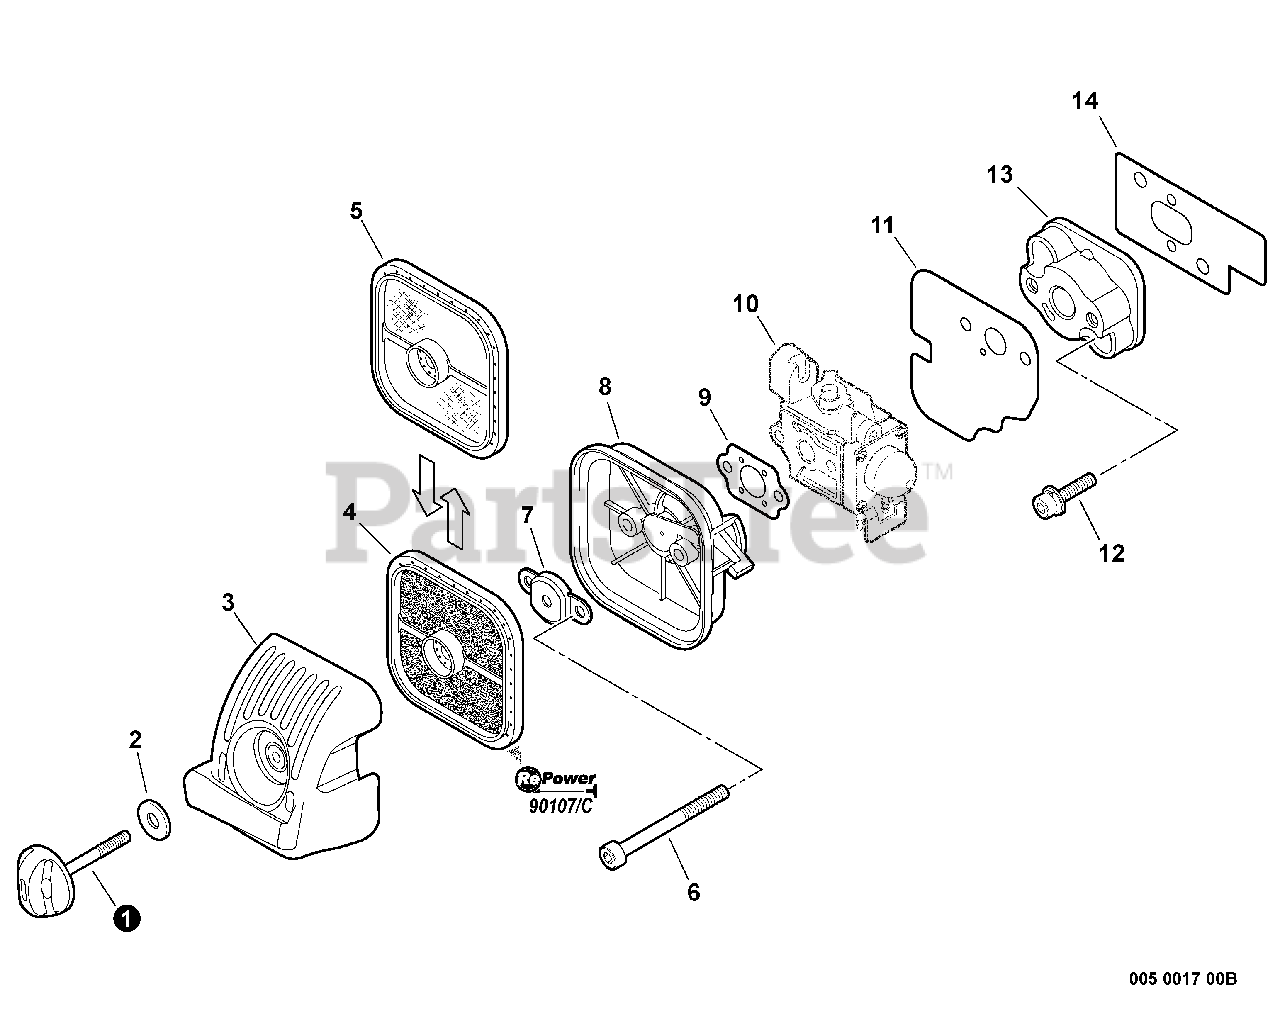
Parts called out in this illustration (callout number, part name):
1	THUMBSCREW
2	WASHER 5.5×16×0.8
3	COVER, AIR FILTER
4	FILTER, AIR - DOUBLE LAYER
5	FILTER, AIR - SINGLE LAYER
6	BOLT 5×60
7	PLATE, PREVENT
8	CASE ASSY, AIR FILTER
9	GASKET, INTAKE
10	CARBURETOR
11	GASKET, INTAKE
12	BOLT 5×25
13	INSULATOR, INTAKE
14	GASKET, INTAKE
16	TUNE-UP KIT - REPOWER
